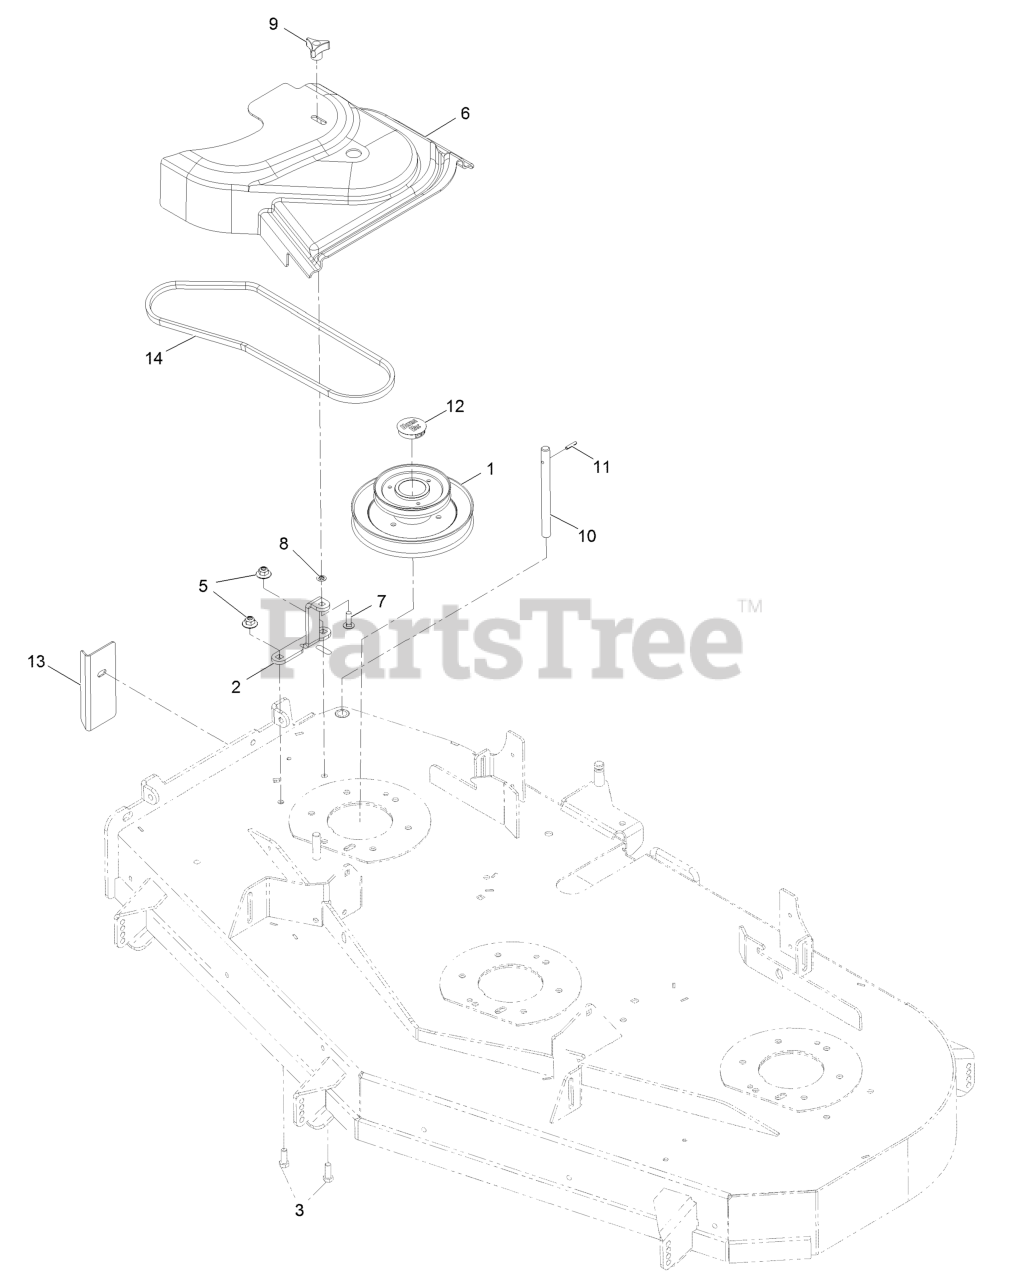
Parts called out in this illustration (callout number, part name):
1	Jackshft- Uv Drive 603
2	Bracket-Belt Cover [black]
3	Screw-HH 3/8-16 X 1
5	Nut-Nyloc 3/8-16 Flg
6	Cover-Belt Uve 60
7	Bolt-Carriage 5/16-18 X 1
8	Ring-Bolt Retaining
9	Knob-3 Prong
10	Shaft-Catcher, Grass
11	Rollpin 3/16 X 7/8
13	Plate-Blocker
14	Belt- 4L Section
